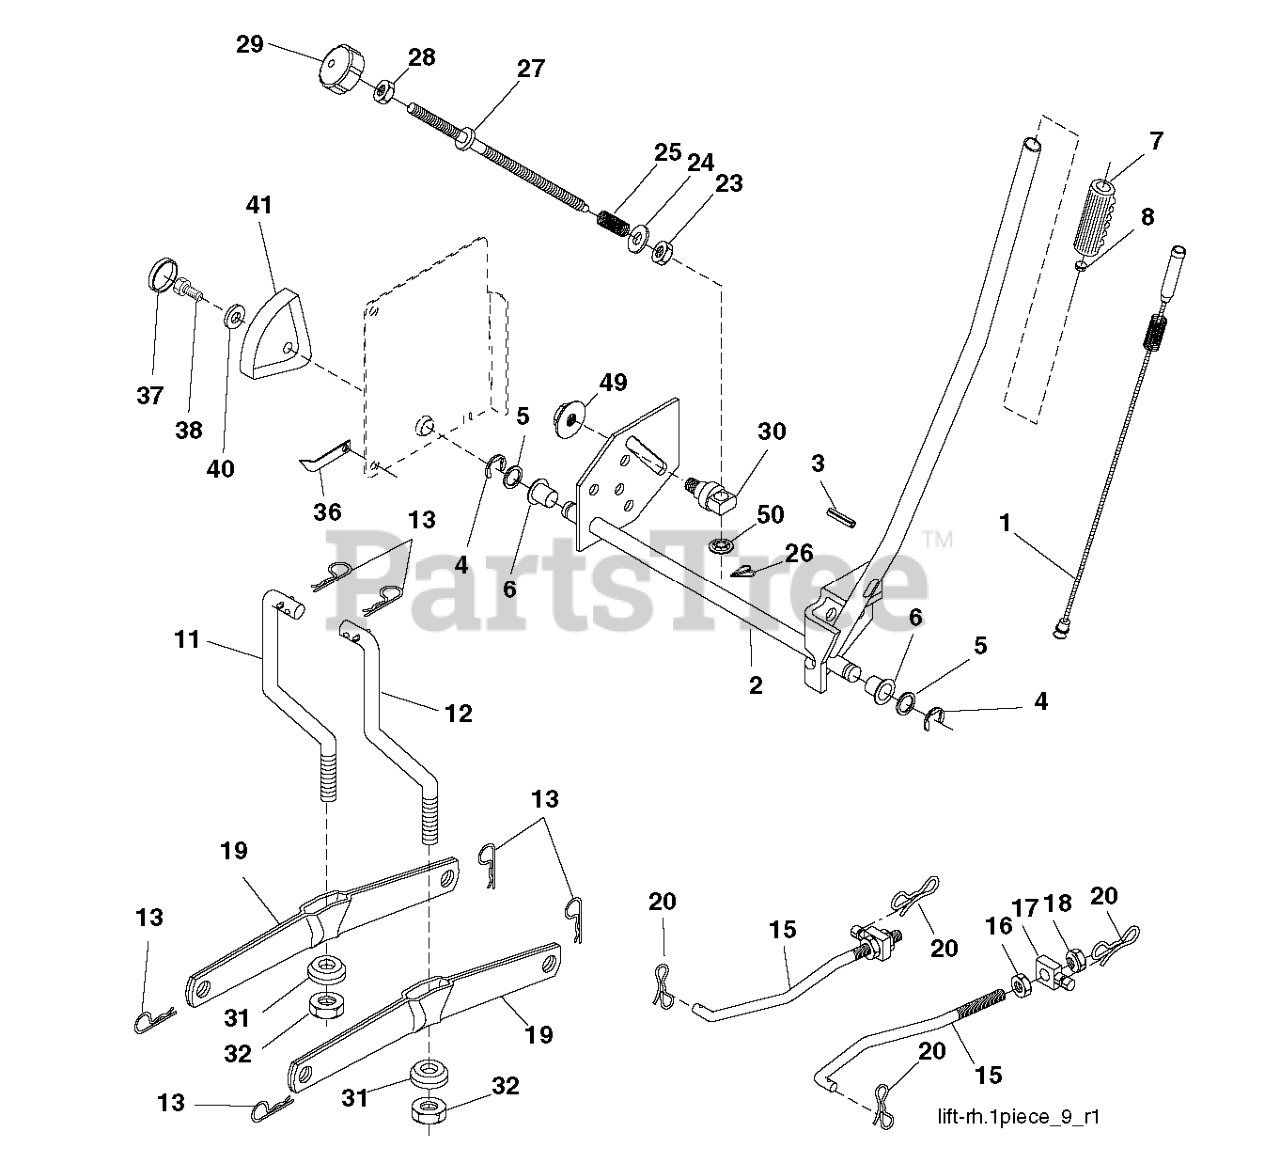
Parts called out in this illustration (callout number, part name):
1	PLUNGER.ASM.LIFT.LVR.BLK.17.32
2	SHAFT ASM R HANDLE
3	PIN GROOVE.
4	RETAINING RING LT
6	BEARING.NYLON
7	GRIP HANDLE
8	PLUNGER BUT KIT
11	LINK
12	LINK
13	RETAINER-SPRNG RB
15	LINK.SUSPENSION.FRONT
16	NUT.HEX.JAM.1/2-13
18	NUT.LK.W/WSH.1/2.
19	ARM.REAR.SUSPENSION
20	PIN.COTTER.7/16.BOW TI.
26	RETAINER CLIP
27	ROD ADJ LIFT
28	NUT
29	KNOB INF 3/8-16
31	BEARING.PIVOT.LIFT
32	NUT CROWNLOCK 3/8-24
36	POINTER, HEIGHT INDICATOR(2 2)
38	SCREW 5/16-18X1
41	HEIGHT INDICATOR
49	NUT
50	NUT PUSH M
